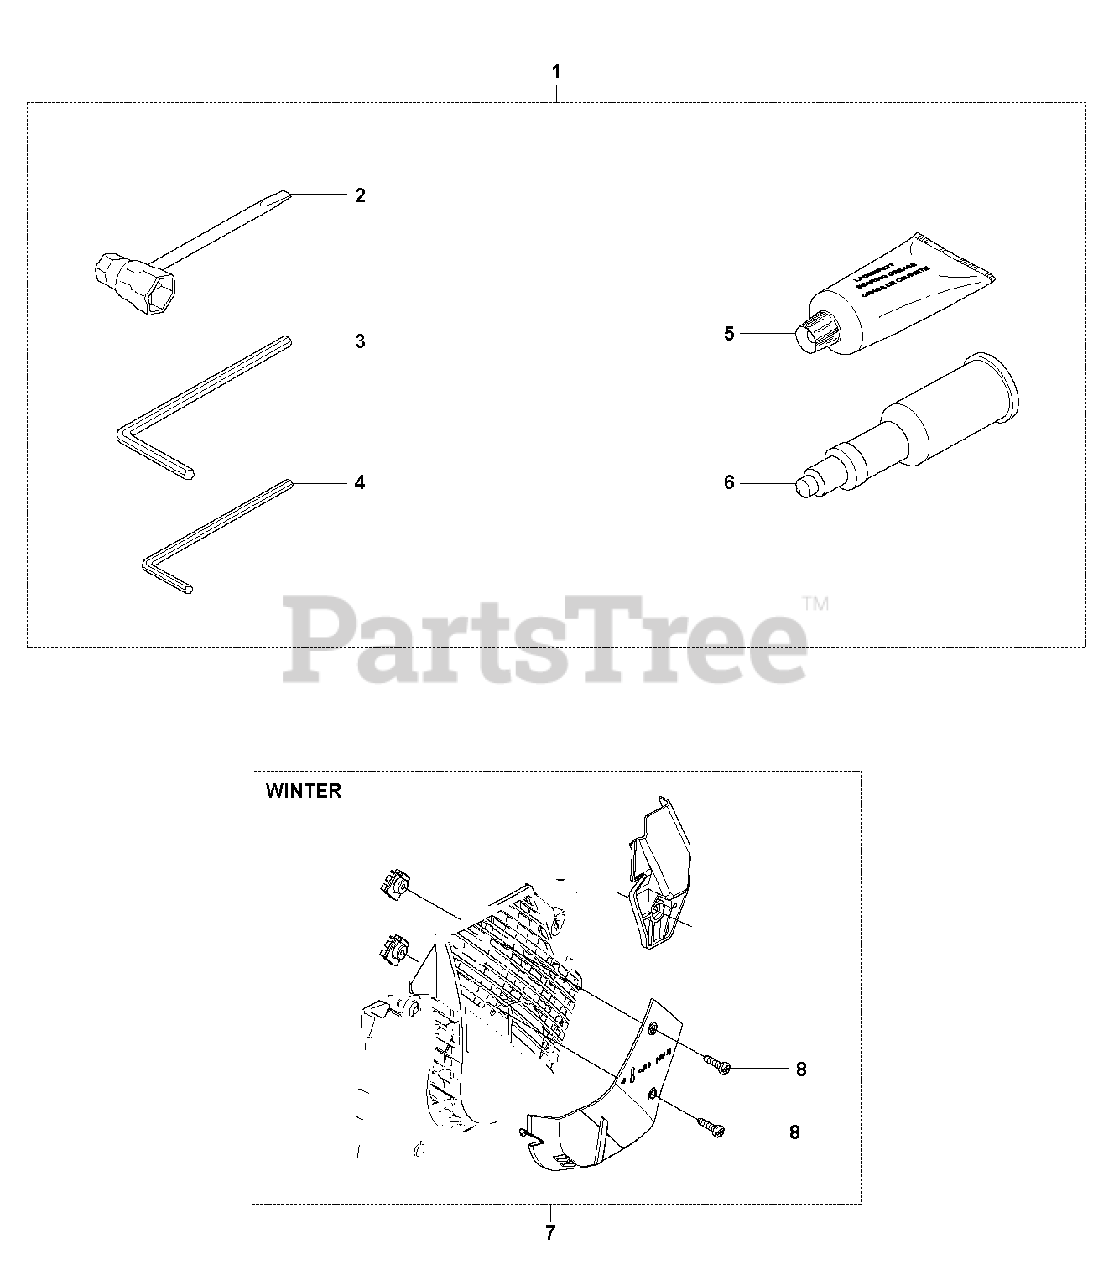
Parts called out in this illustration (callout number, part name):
1	TOOL KIT
2	COMBI TOOL
3	L-SPANNER
4	L-SPANNER
5	GREASE
6	GREASE GUN
7	KIT
8	SCREW
